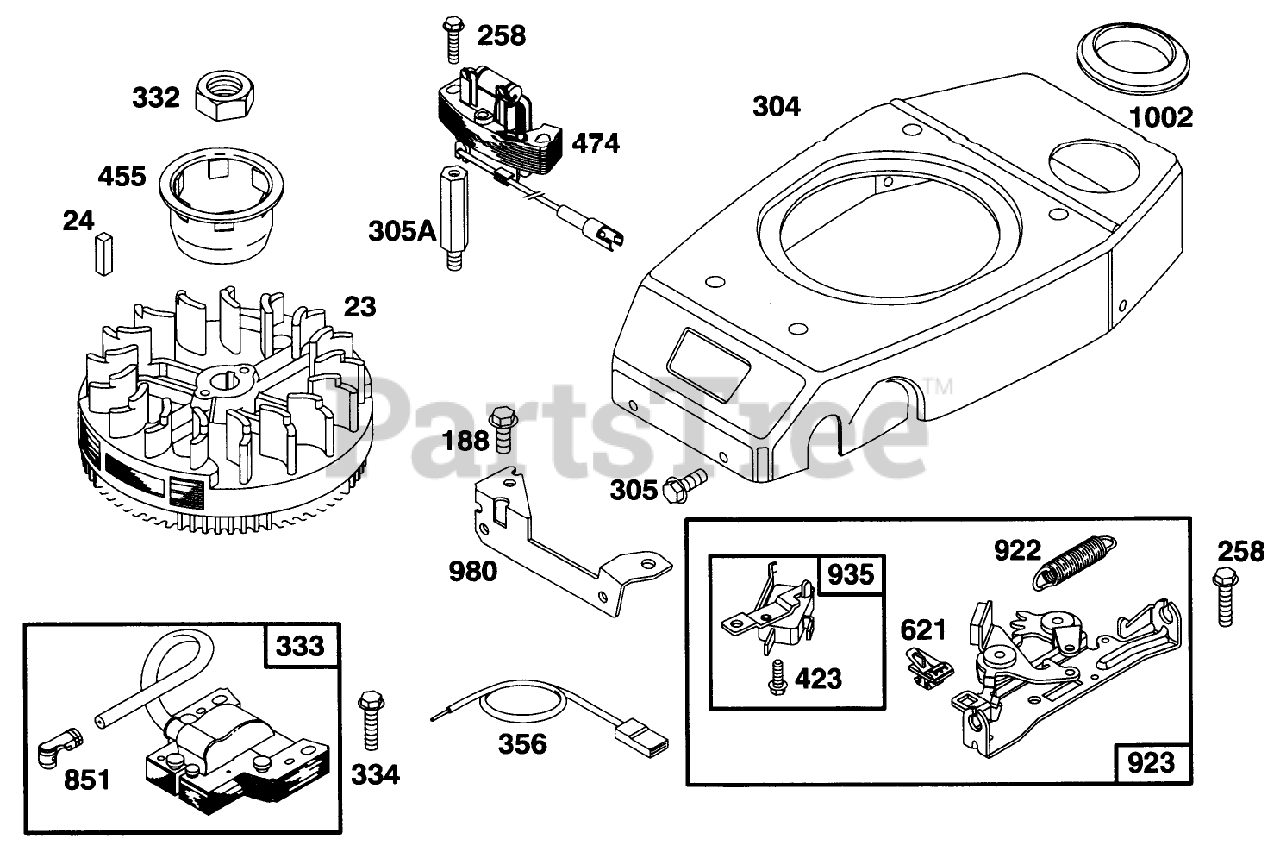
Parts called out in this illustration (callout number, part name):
23	FLYWHEEL - MAGNETO
24	KEY - FLYWHEEL
305	SCREW - HEX HEAD
332	NUT - HEXAGON
334	SCREW - SEM
356	WIRE - GROUND
455	CUP - STARTER
621	STOP SWITCH
980	BRACKET-BLOWER HSG
